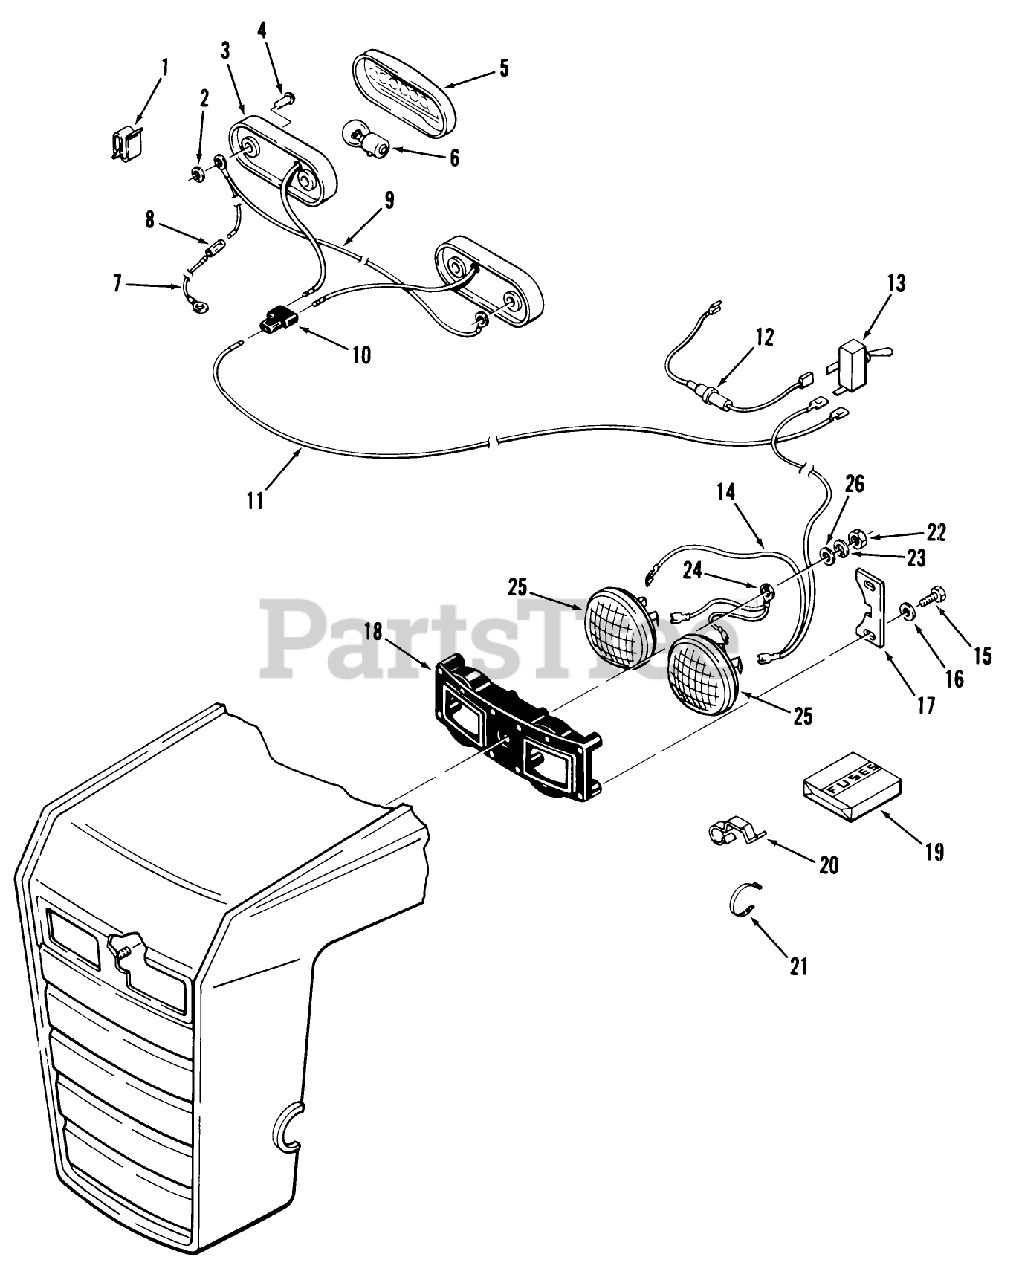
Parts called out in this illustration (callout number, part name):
2	WASHER
6	Bulb
13	SWITCH-LIGHTS
14	WIRE-HEADLIGHTS
25	HEADLAMP
26	WASHER 5/16 SAE
